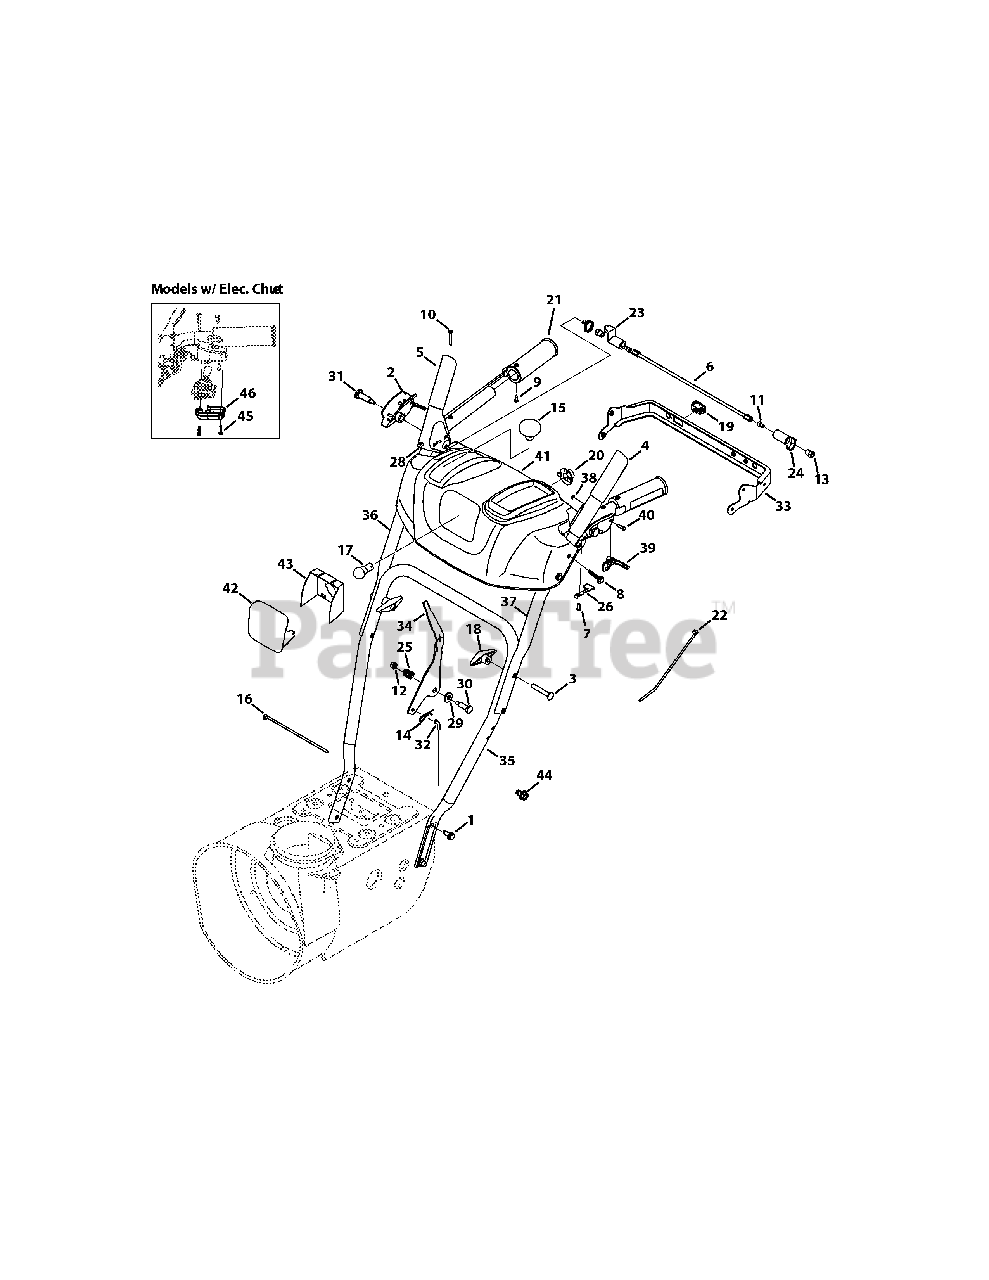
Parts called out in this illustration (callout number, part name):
1	Screw, Taptite, 5/16-18 x .750
2	Clutch Lock, RH (Elec. Chute)
3	Screw, Carriage, 5/16-18 x 2.50
4	Auger Engage, Red, LH
5	Drive Engage, Red, RH
7	Screw, Plastite, 8-16 x .50
8	Screw, Taptite, 1/4-20 x 1.625
9	Screw, 10-16 x 0.625
10	Screw, 10-24 x 1.375
11	Screw, 1/4-20 x .50
12	Nut, Flangelock, 1/4-20
13	Nut, Hex, 1/4-20
14	Click Pin, .092 x 1.64
15	Shift Knob
16	Cable Tie, 7"
18	Wing Knob, 5/16-18
19	Heated Grip Switch
20	Lamp Socket
21	Heated Grip
22	Cable Tie, Push Mount
23	Plate, Lock
24	Cam, Clutch Lock
25	Compression Spring, .39 x .60 x .88
26	Clutch Lock Spring
27	Torsion Spring, 0.8156 x .3038
28	Rubber Bumper
29	Washer, Flat, .385 x .87
30	Screw, Shield, .374 x 1.05
31	Screw, Shoulder, .437 x 1.345 x 1/4-20
32	Speed Selector Cable
35	Lower Handle
36	Upper RH Handle
37	Upper LH Handle
39	Steering Trigger Control, Red
40	Steering Trigger Pin, 3/16
41	Handle Panel, Elec. Chute
42	Lens Panel
43	Lens Label
44	Screw, TT, 1/4-20 x .500 (For ground wire)
45	Screw, .159 OD x .610
46	Housing Cover (Elec Chute)
